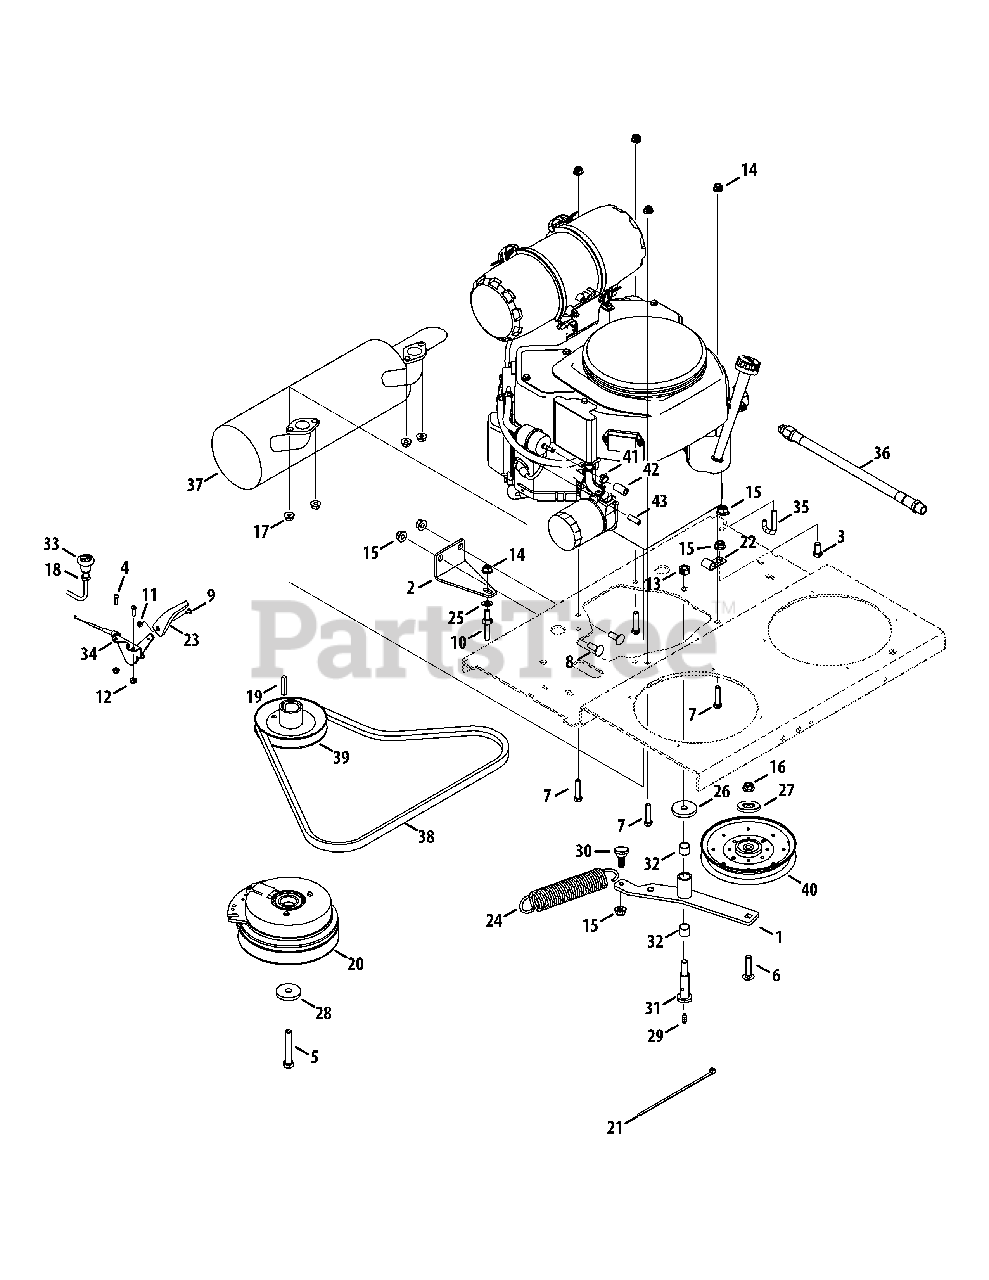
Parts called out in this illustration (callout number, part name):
1	Idler Bracket
2	Clutch Retainer Bracket
3	Hex Cap Screw, 3/8-16 x .75
4	Screw, #10-24 x .625
5	Hex Cap Screw, 7/16-20 x 2.75
6	Carriage Bolt, 3/8-16 x 1.00
7	Hex Cap Screw, 5/16-18 x 1.50
8	Carriage Bolt, 3/8-16 x 1.00
9	Screw, #8-32 x .375
10	Stud, Pivot Ball Joint
11	Nut, #8-32, Hex
12	Nut, #10-24, Hexlock
13	Nut, 7/16-14, Hexlock
14	Nut, 5/16-18, Flangelock
15	Nut, 3/8-16, Flangelock
16	Nut, 3/8-16, Flangelock
17	Nut, M8-1.25, Hexlock
18	Jam Nut, 3/8-24
19	Key, 1/4 x 1.50
20	Electric PTO Clutch
21	Cable Tie
22	Clip, .407 x 1.80
23	Throttle Control Knob
24	Extension Spring, 1.5 x 7.5
25	Washer, .344 x .688 x .065
26	Washer, .471 x 1.50 x .225
27	Pulley Cap
28	Washer, .471 x 1.50 x .225
29	Grease Fitting
30	Shoulder Screw, .625 x .302, 3/8-16
31	Shoulder Bolt, .625 x 1.95, 7/16-14
32	bearing, .638 x .753 x .615
33	Choke Control Cable
34	Throttle Cable
35	Transmission Spring Hook
36	Oil Drain Hose
37	Muffler (FX850)
37	Muffler (FX730)
38	Belt
39	Drive Pulley
40	Idler Pulley
41	Hose Clamp, .500 Dia.
42	Fuel Hose., 1/4
